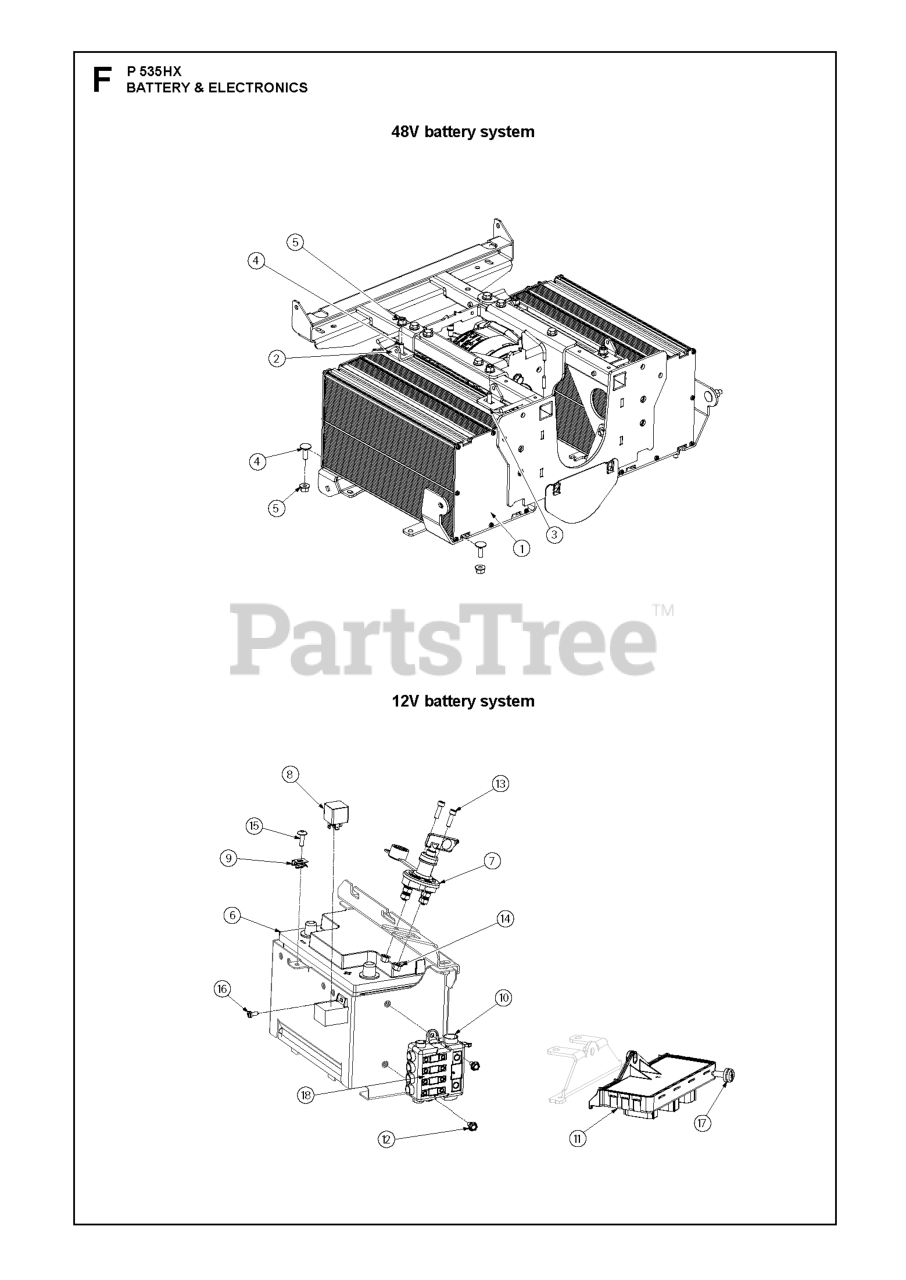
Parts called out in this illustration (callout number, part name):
5	NUT FLANGE
12	SCREW EHHFM
13	SCREW MC6S 6X20
14	NUT FLANGE
